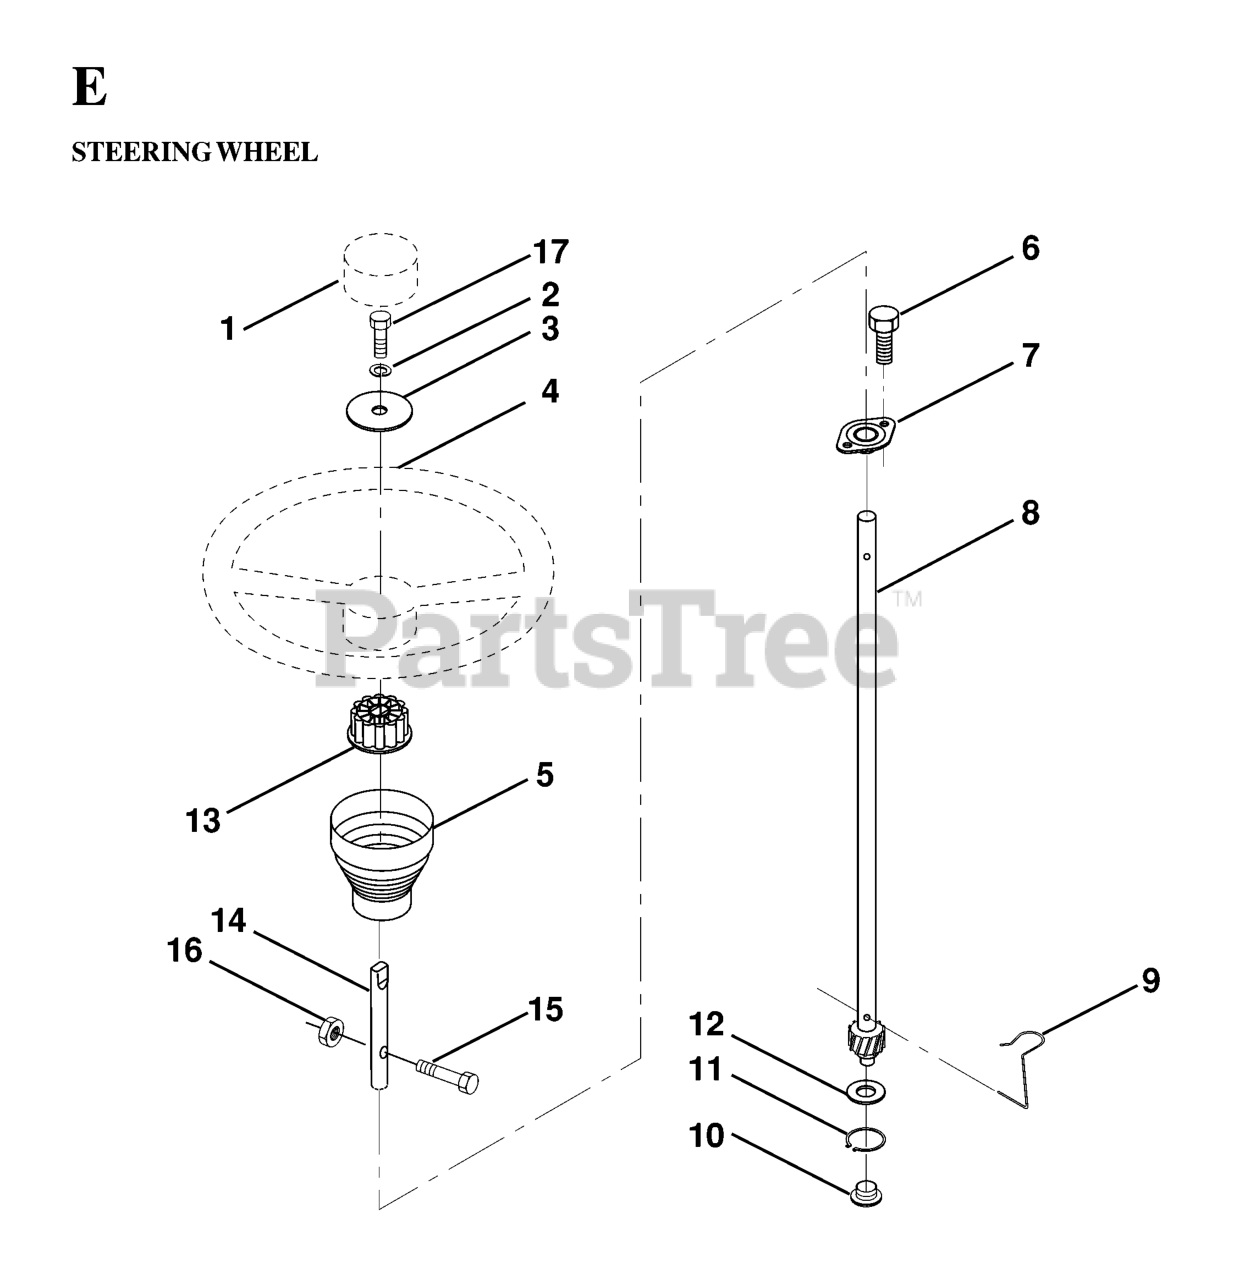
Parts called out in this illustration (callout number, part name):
1	INSERT,STR WHEEL
2	WASHER, LOCK 3/8
3	WASHER T
4	STEERING WHEEL
5	STEERING SLEEVE
6	SCREW.TT.#10-32X.5.3/8.FLANGE
7	BUSHING
8	STEERING SHAFT
9	STEERING CLIP
10	BUSHING STEER LWR
13	ADAPTER LT
14	EXT SHAFT STEERING
15	BOLT.5/16-18X1-1/4 FULL.THREAD
16	NUT.71038.31-18.HEX.NYLOCK
